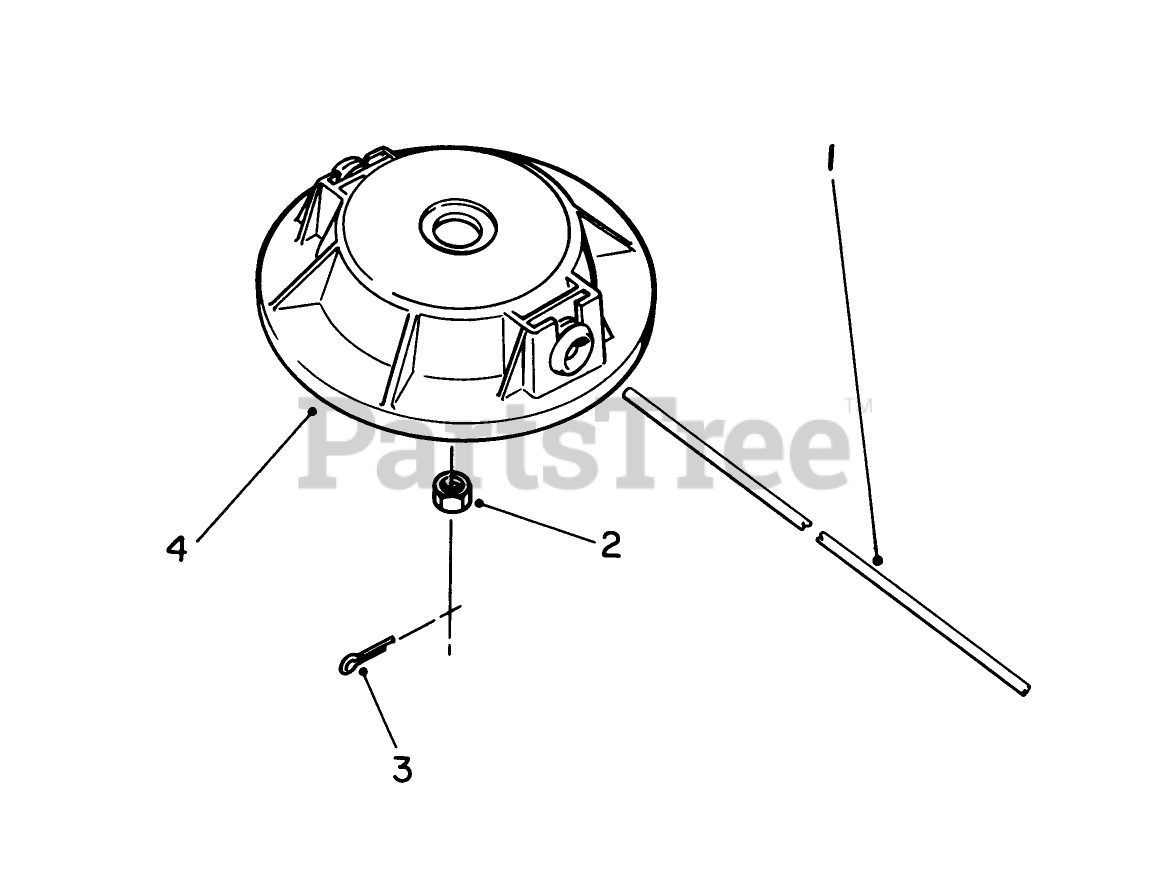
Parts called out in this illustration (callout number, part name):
1	LINE PACK (100)
3	PIN-COTTER
4	CUTTER HEAD-PLASTIC
